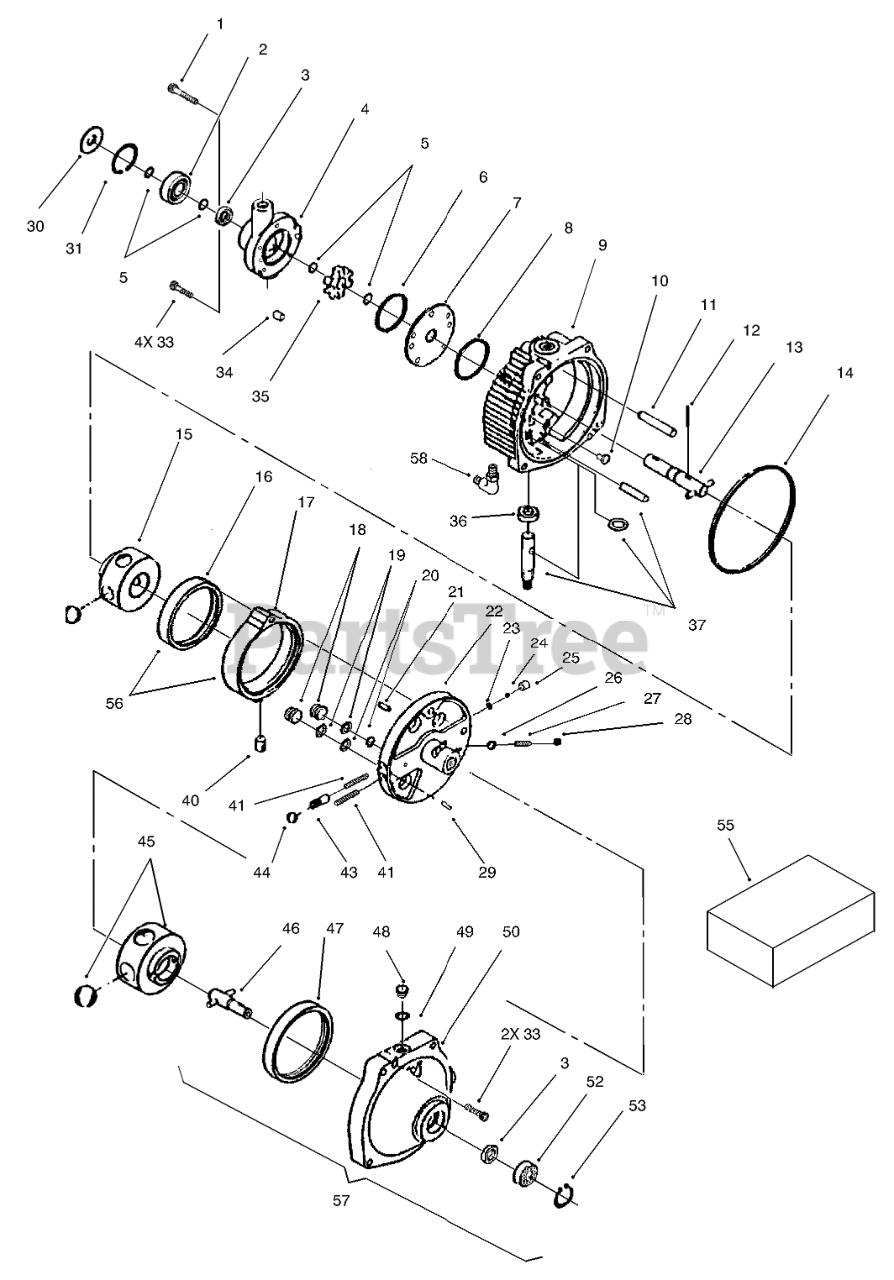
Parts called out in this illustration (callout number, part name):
1	CAPSCREW
2	BEARING
3	SEAL-OIL
4	PUMP ASM
7	PLATE
9	COVER SUB ASM
10	BUTTON
13	SHAFT
15	ROTOR
16	PUMP-RACE
17	RING-CAM
18	PISTON
20	O-RING
22	PINTLE
27	SPRING
30	SHIELD-GRASS
31	RETAINING-RING
33	SCREW-HH
35	CARRIER
36	SEAL-OIL
37	SHAFT KIT
40	INSERT
41	SPRING
45	ROTOR
46	SHAFT
48	PLUG ASM
49	O-RING
50	Body
52	Bearing
55	SEAL KIT
56	CAM RING ASM
57	Body ASM
58	FITTING-90 DEGEE
